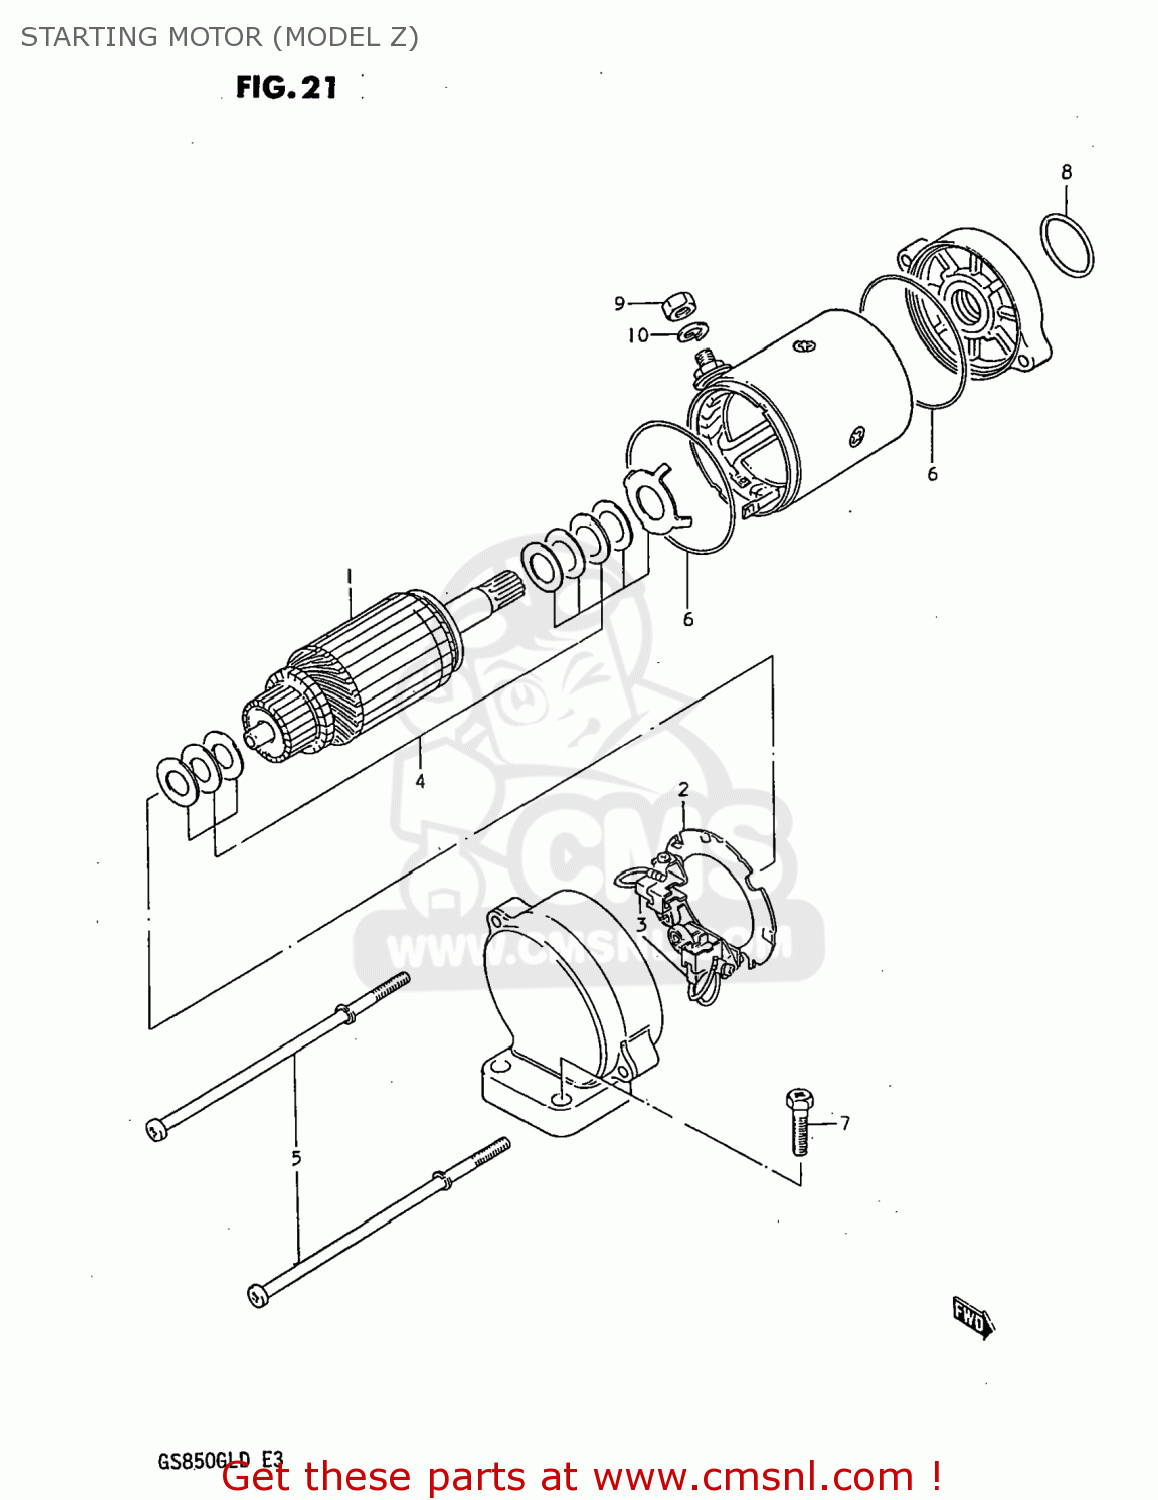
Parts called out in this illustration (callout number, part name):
1	ARMATURE
2	HOLDER ASSY
3	BRUSH SET
4	SHIM SET
5	BOLT,STARTING MOTOR HOUSING
6	O RING
7	SCREW (6X25)
8	O RING(D:2,ID:24.5)
9	NUT 6MM
10	LOCK WASHER
